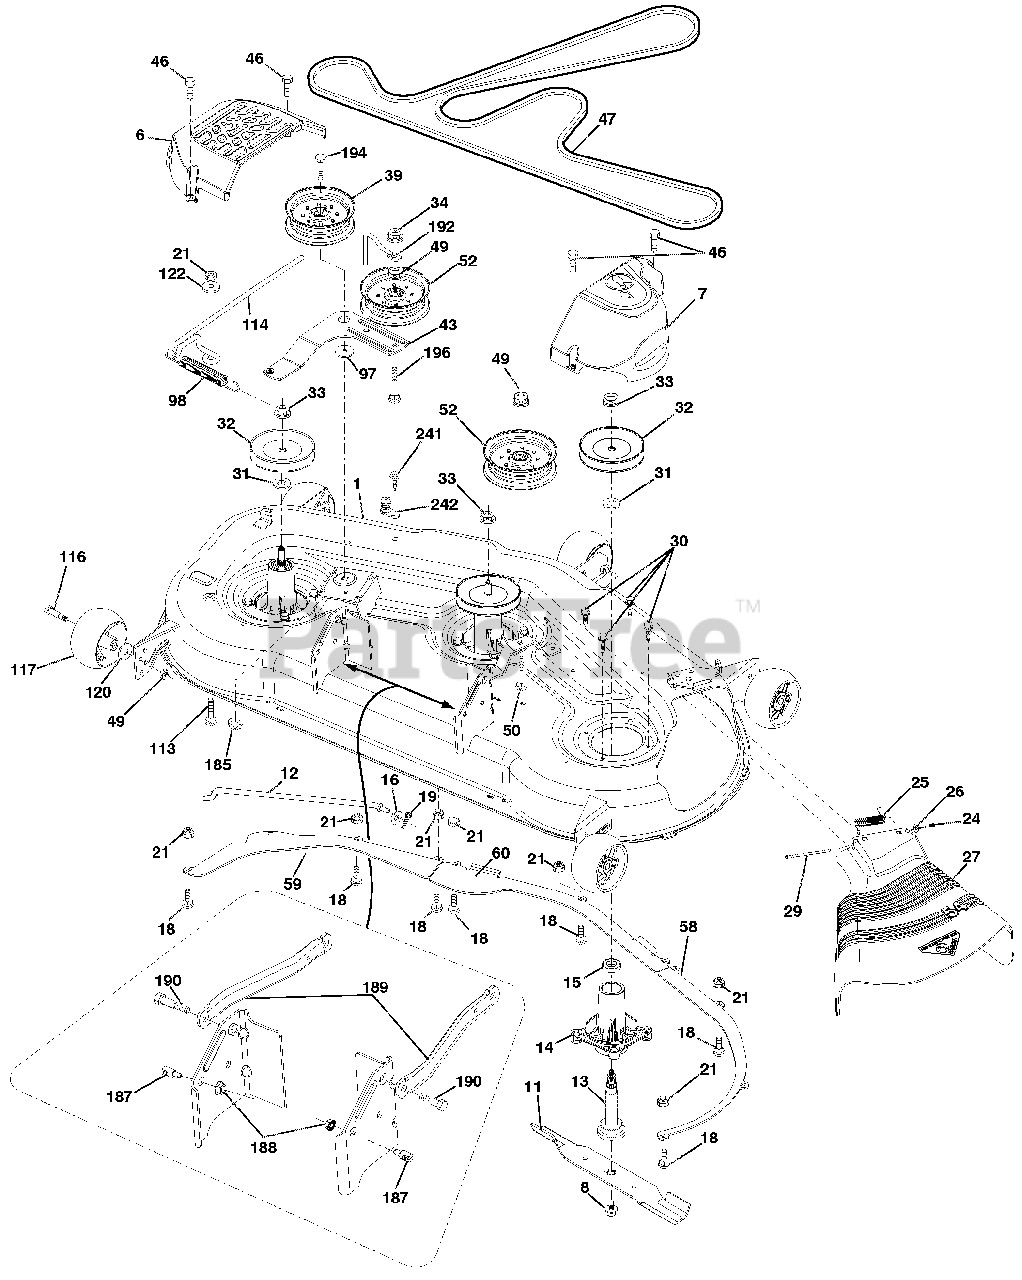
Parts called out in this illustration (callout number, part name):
1	DECK WELDMENT MOWER
6	COVER.MANDREL.LH.54"2006
7	COVER.MANDREL.RH.54"2006
8	BOLT/WASHER ASM.7/16-20.UNF
11	BLADE.BAGGING.54"
12	ROD ANTI-SWAY
13	SHAFT ASM.MANDREL.48/54"SVC
14	HOUSING.MANDREL.4PT.SERVICE
15	BEARING.BALL.MANDREL
16	Washer 13/32 x 13/16 x 12 Ga.
18	BOLT.RDHD.SQNK.5/16-18 X 5/8
19	PIN.COTTER.5/16.BOW TIE LOCK
21	Nut, Hex, Crownlock 5/16-18
24	CAP.SLEEVE..80X.112.BLK.MOWER
25	SPRING.TORSION.48"
26	NUT.PUSH.PHOS.& OIL
27	DEFLECTOR SHIELD
29	ROD.HINGE.42/46"
30	SCREW.THD ROLL.DOD PT.HEX
31	WASHER.SPACER.MANDREL
32	MANDREL.PULLEYS.42,44,50
33	NUT.FLANGE.LOCK.TOP
34	Nut, Hex, Crownlock 3/8-16
39	PULLEY.IDLER.4.50.HUB.SPECIAL
43	ARM.ILDER
46	SCREW.THD.ROLL.1/4-20 X 5/8
47	BELT.DRIVE.54"2006
49	Nut, Hex, Flangelock 3/8-16
50	BOLT.RD.HD.SQ.NK.3/8-16UNC X 2
52	PULLEY.IDLER.4.50.RAW
58	BAFFLE.RIGHT.54"
59	BAFFLE.LEFT.54"
60	BAFFLE.CENTER.54"MOWER
97	WASHER.FLAT.HARDENED
98	SPRING.DRIVE.DECK.2006
113	BOLT.CARR.5/16-18UNC X 1
114	ROD.TENSION.RELIEF
116	BOLT.SHOULDER.3/8-16X3-5/8.GR5
117	WHEEL.GAUGE.RALLY.
120	WASHER.13/32 X 1-1/4 X 12 GA.
122	BUSHING.RELIEF.TENSION
185	NUT.LOCK.FLANGE.7/16-14.GR5
187	STUD.FASTNER.W/'D'ANTI-ROTATIO
188	Nut, Lock Hex Flange 5/16-18 u
189	ARM.SUSPENSION.MOWER.REAR
190	BOLT.SHOULDER
192	KEEPER.BELT.IDLER.54"TL
194	BOLT CARR SQNK 3/8-16 X 2-1/4
196	BOLT.RDHD.SQNK.3/8-16X2-1/2.G5
242	PORT WASHOUT
